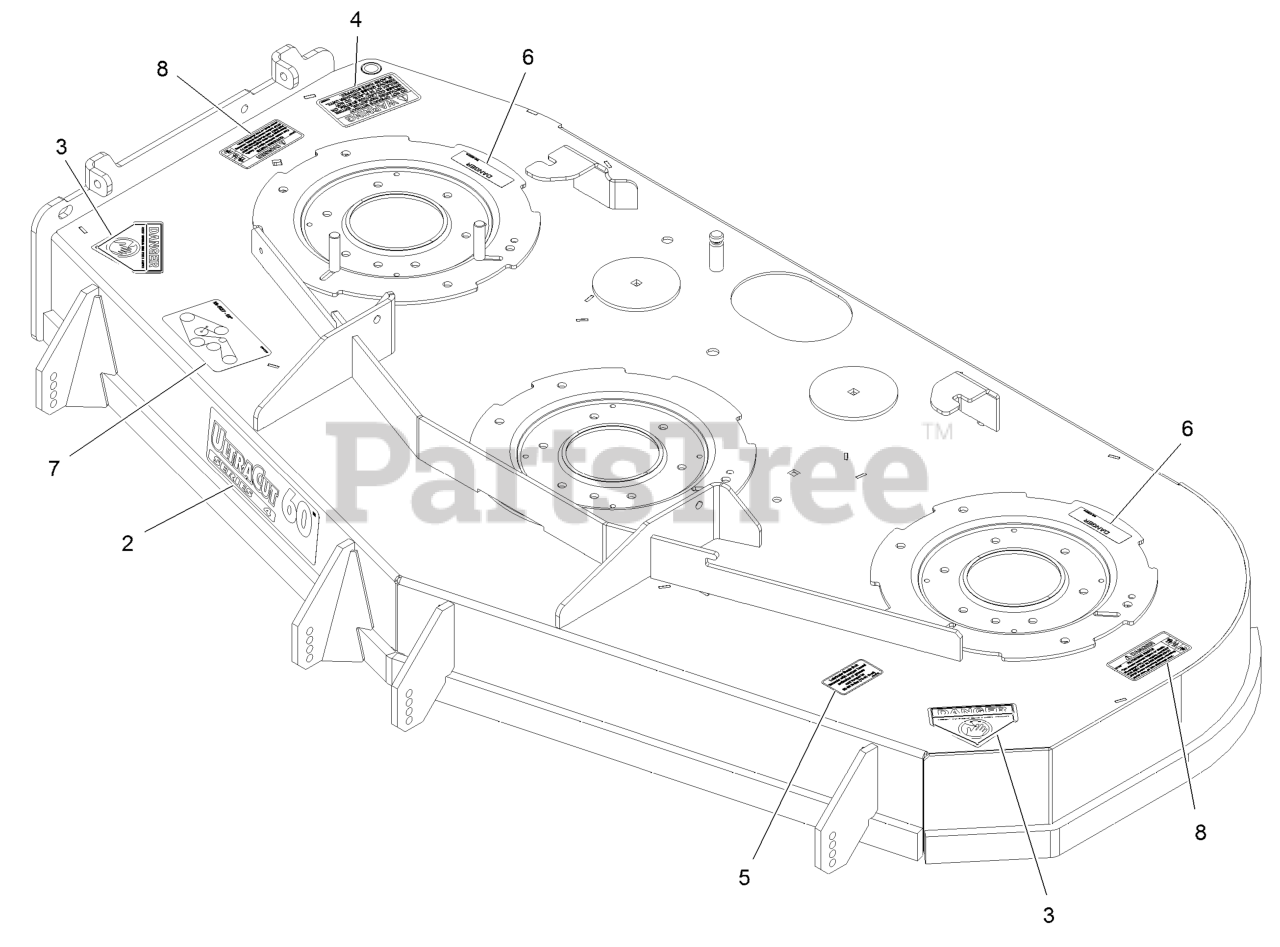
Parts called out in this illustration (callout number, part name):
2	DECAL,ULTRACUT 60 SERIES
3	DECAL-DANGER
4	DECAL-WARNING, DISCHARGE
5	DECAL,BOLT TORQUE
6	DECAL-COVER, MISSING
7	DECAL-BELT ROUTING
8	DECAL-ROTATING PARTS
